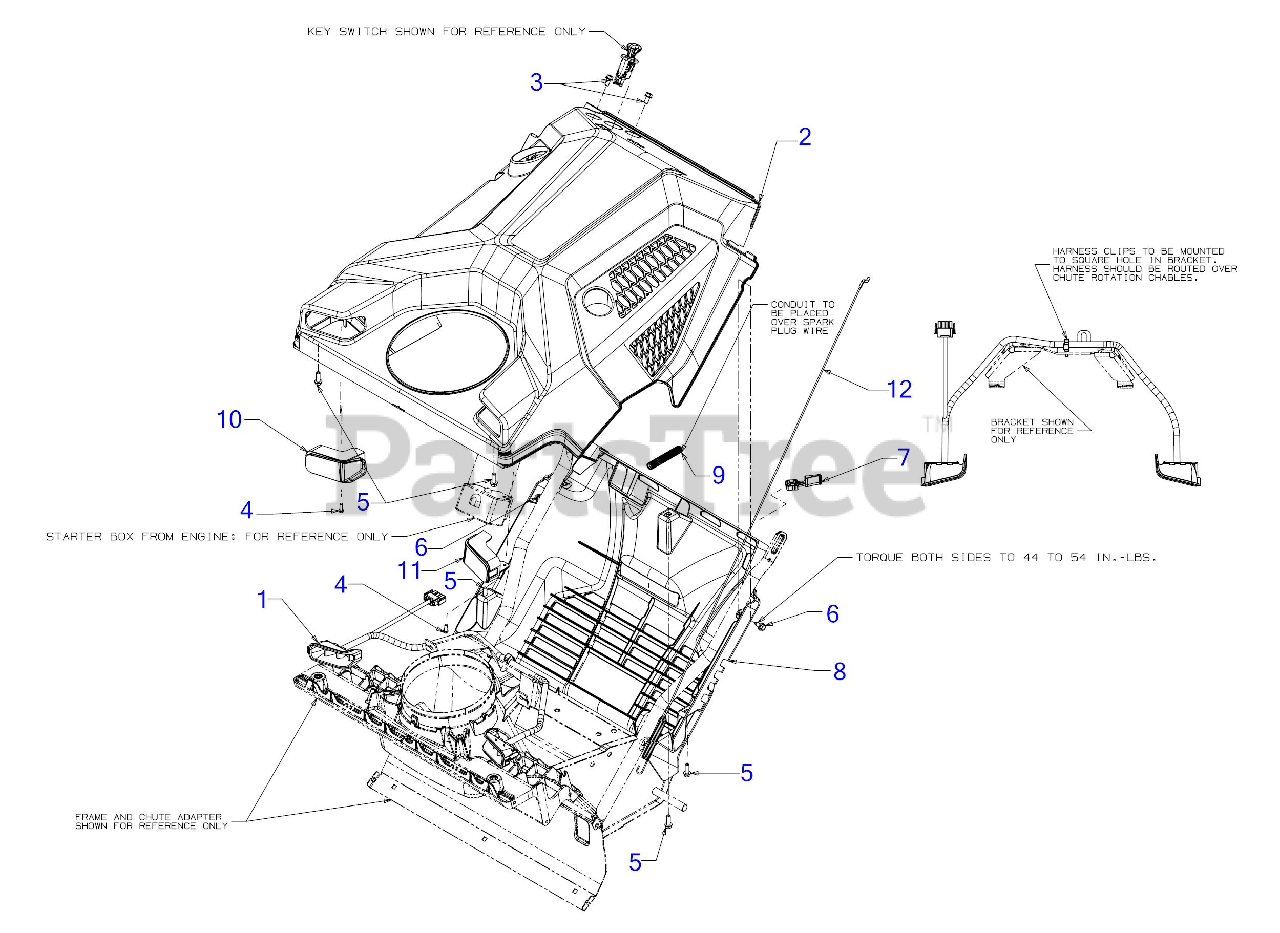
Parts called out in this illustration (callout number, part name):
1	LED HEADLIGHT ASSEMBLY
2	COVER ASSEMBLY BLACK
3	HEX SCREW 1/4-15 x .50
4	SCREW #8-16 x .50
5	SCREW 1/4-15 x .750
6	SCREW 1/4-20X.625
7	CHOKE EXTENION LEVER
8	BOTTOM COVER
9	CONVOLUTED CONDUIT
10	LED LENS RH
11	LED LENS LH
12	AUGER CLUTCH CABLE 37.05"
